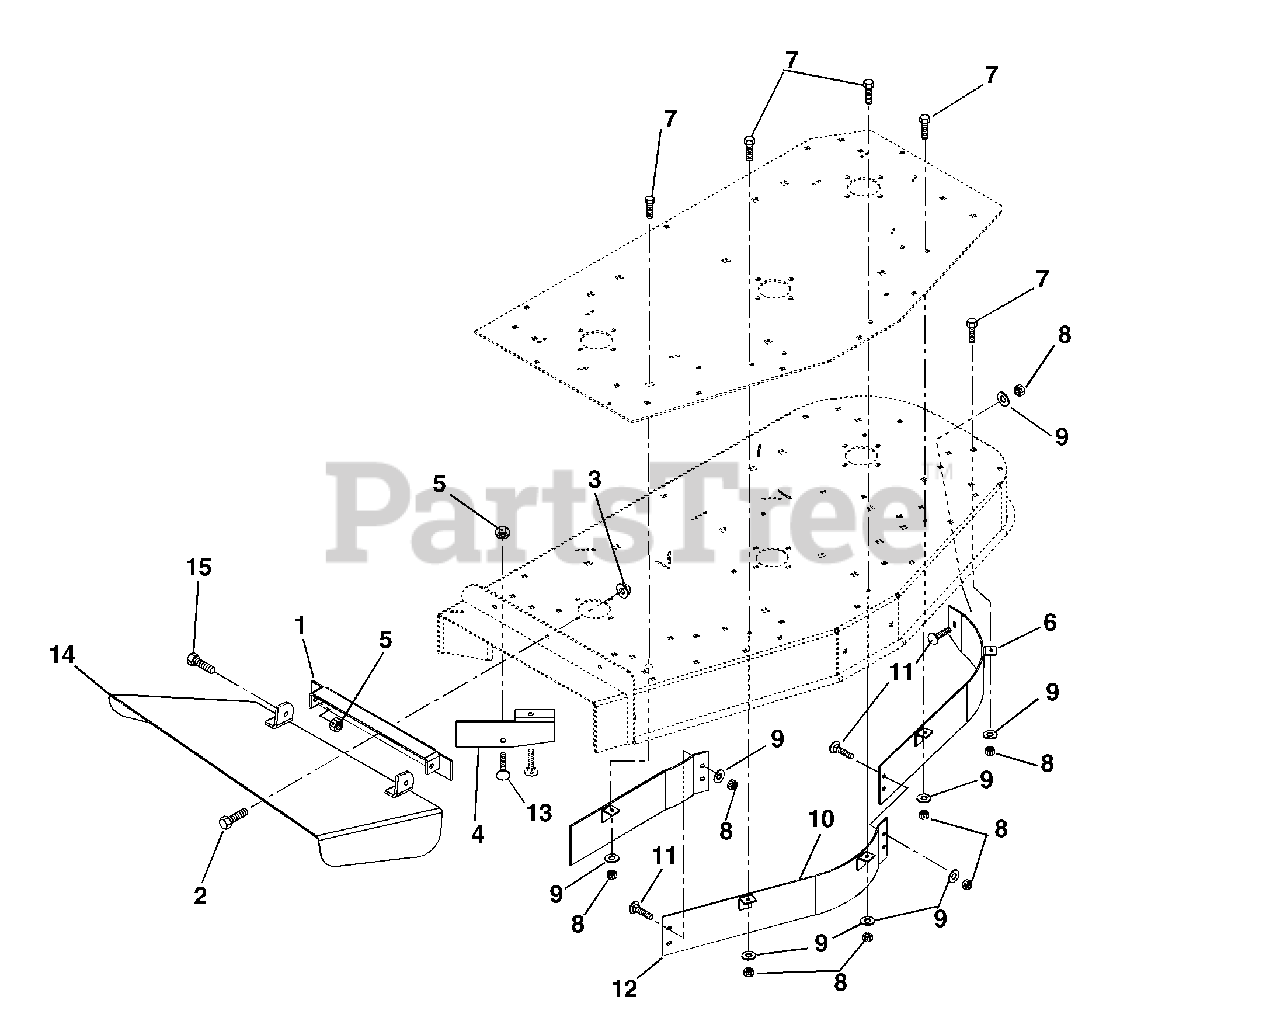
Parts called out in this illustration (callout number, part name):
1	Weldment, Discharge Chute Bracket
2	Bolt-Hex .38-16 x 1.00 Grade 5
3	Nut-Locking-Flange .38-16
4	Deflector 50"
5	Nut-Locking-Center .38-16
6	Weldment, 50" Left Hand Baffle-Upper
7	Bolt-Hex .31-18 x 1.00 Grade 5
8	Nut-Locking-Nylon .31-18
9	Washer-Flat-Steel .312 x .734 x .065
10	Weldment, 50" Center Baffle-Up
11	Bolt-Round Head Square Neck .31-18 x .75 Grade 5
12	Weldment, 50" Right Hand Baffle-Upper
13	Bolt-Round Head Square Neck .38-16 x 1.00 Grade 2
14	Weldment, Discharge Chute 50"
15	Bolt-Hex .38-16 x 1.00 Grade 5
16	50" Discharge Cover
17	50" Mulch Kit
